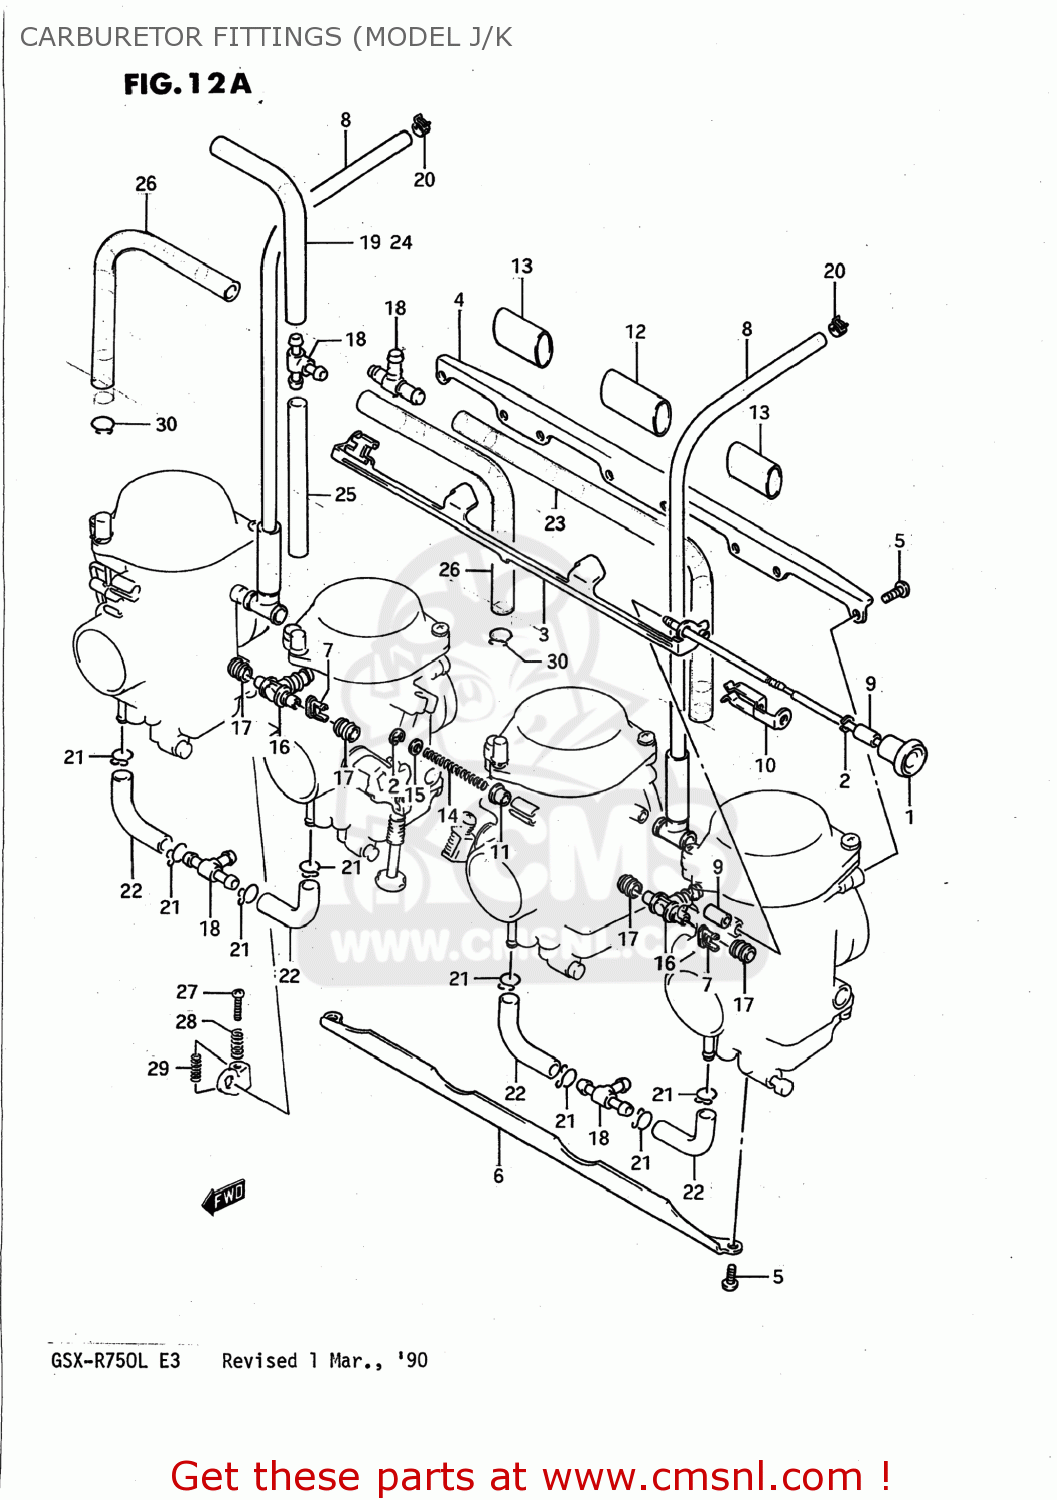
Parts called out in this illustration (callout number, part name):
1	SHAFT ASSY,STARTER
2	E RING
3	LEVER
4	PLATE
5	SCREW
6	PLATE
7	HOLDER
8	HOSE
9	SPACER
10	PLATE
11	RING
12	HOSE
13	HOSE
14	SPRING
15	WASHER
16	NIPPLE
17	HOSE
18	NIPPLE
19	HOSE
20	CLIP
21	CLIP
22	HOSE
23	HOSE
24	HOSE
25	HOSE
26	HOSE
27	SCREW
28	SPRING
29	SPRING
30	CLIP
